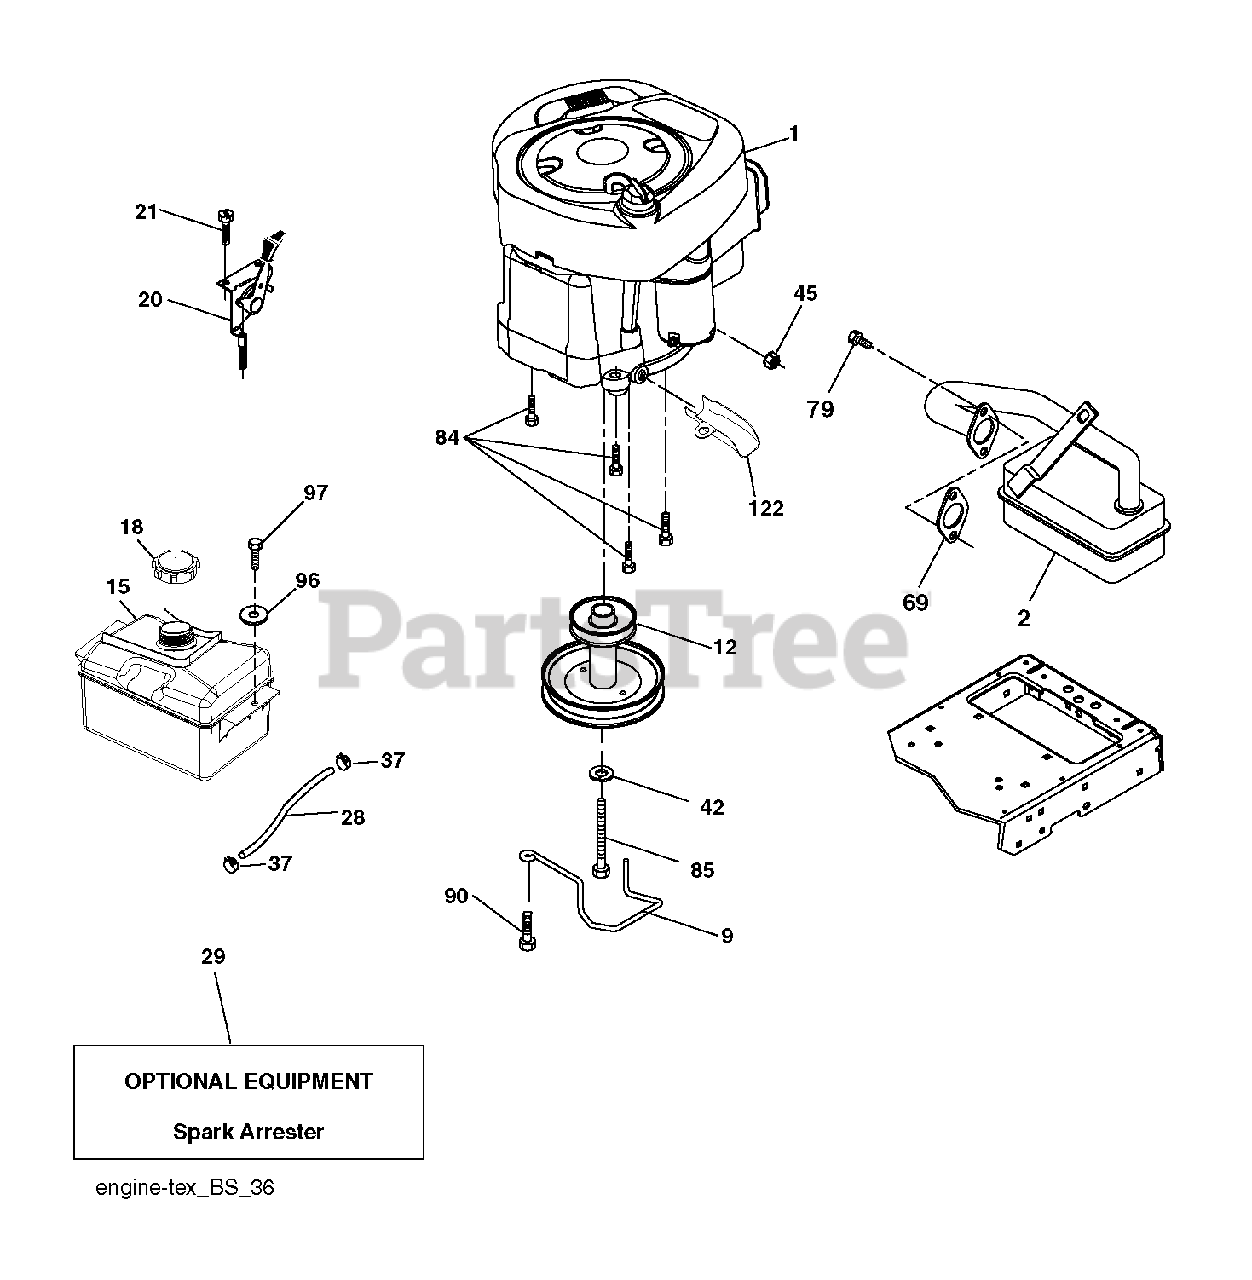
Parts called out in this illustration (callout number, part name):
2	MUFFLER.B&S.MODEL.21.11HP.OHV
9	KEEPER.BELT.ENGINE.3.25 (3 2)
12	PULLEY.ENG.CL.MECH.SLVR.LT/YT
15	RP TANK FUEL FRT 1.5 GAL
18	CAP ASM.FUEL.2.25"FR.
20	CONTROL.TH/CK.C.
21	SCREW.#10 X 0.750.BOS
28	LINE.FUEL.20
29	KIT.SPARK ARRESTOR 794945 B&S
37	HOSE CLAMP
42	LOCKWASHER
45	NUT
69	REPL BY 532 27 22-93
79	SCREW.SOCKET HD.5/16-1
84	SCREW.3/8-16
85	BOLT HEX 7/16-20X4-1/4"
90	SCREW 3/8-16X1
97	SCREW HEXWSHR 1/4-20X3/4
122	EXTENSION DRAIN OIL
